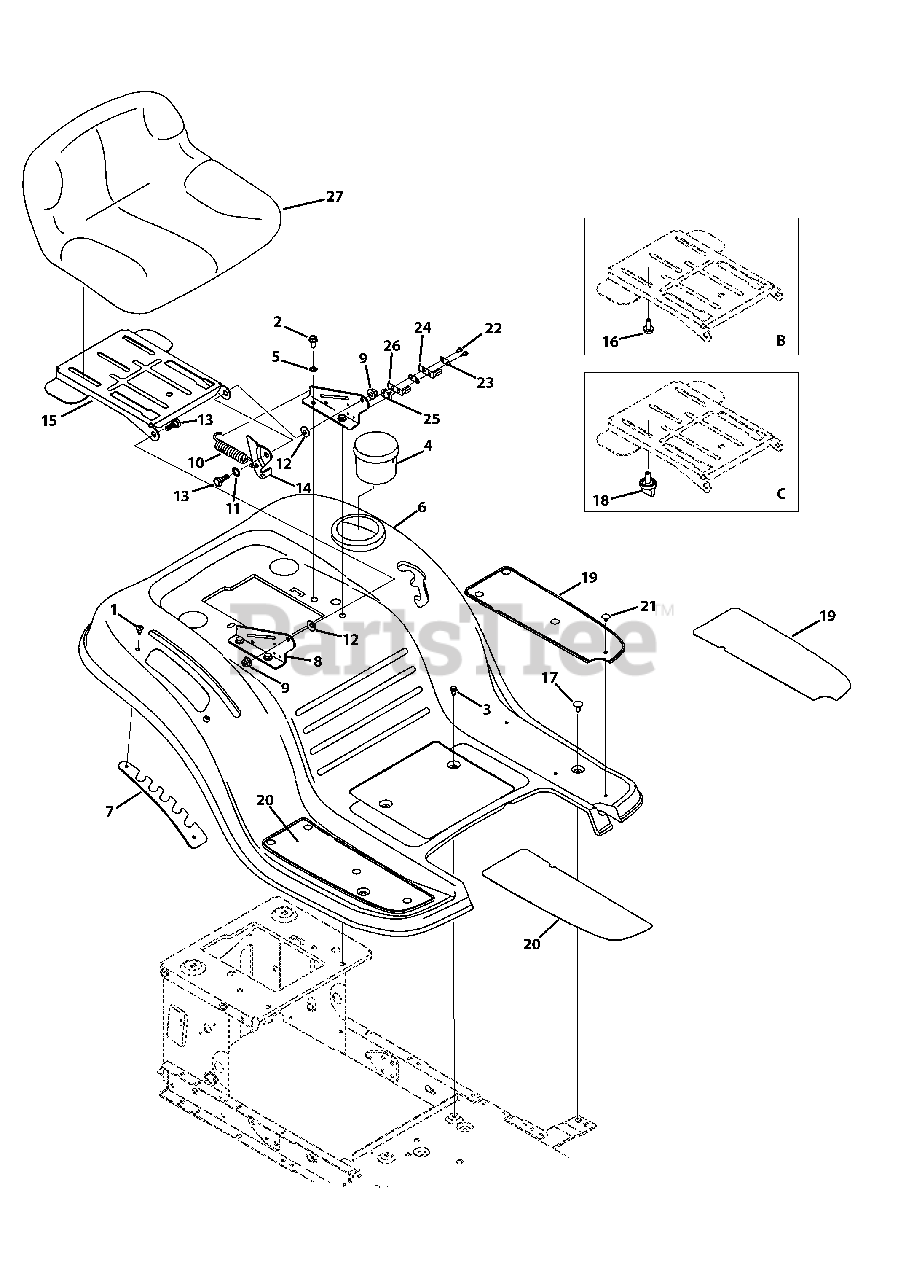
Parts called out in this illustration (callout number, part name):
1	Screw, 1/4-20 x .500
2	Screw, 5/16-18 x .750
3	Screw Pan Torx Head, 1/4-20 x .500
4	Cup Holder
5	Loack Washer, 5/16
6	Fender
7	Lift Adjuster Bracket
8	Seat Mount Bracket
9	Flangelock Nut, 5/16-18
10	Extension Spring
11	Flat Washer, .510x .750 x .033
12	Bell Washer, .340 x .872 x .060
13	Shoulder Screw, 5/16-18 x .437 x .268
14	Lift Seat Bracket
15	Pivot Seat Manual Adjust Bracket
16	Hex Head Flange, 3/8-16 x .875
17	Screw Carriage, 1/4-20 x .62
18	Knob, 3/8-16 x .875
19	Foot Pad, LH
19	Foot Pad, Abrasive, LH
20	Foot Pad, RH
20	Foot Pad, Abrasive, RH
21	Ratchet Clip, .250 x .500
22	Screw, 8-18 x .500
23	Insulator Plate
24	Outer Seat SPring
25	Insulator Boss Plate
26	Inner Seat Spring
27	Medium Back Seat, Black, Set-up B
